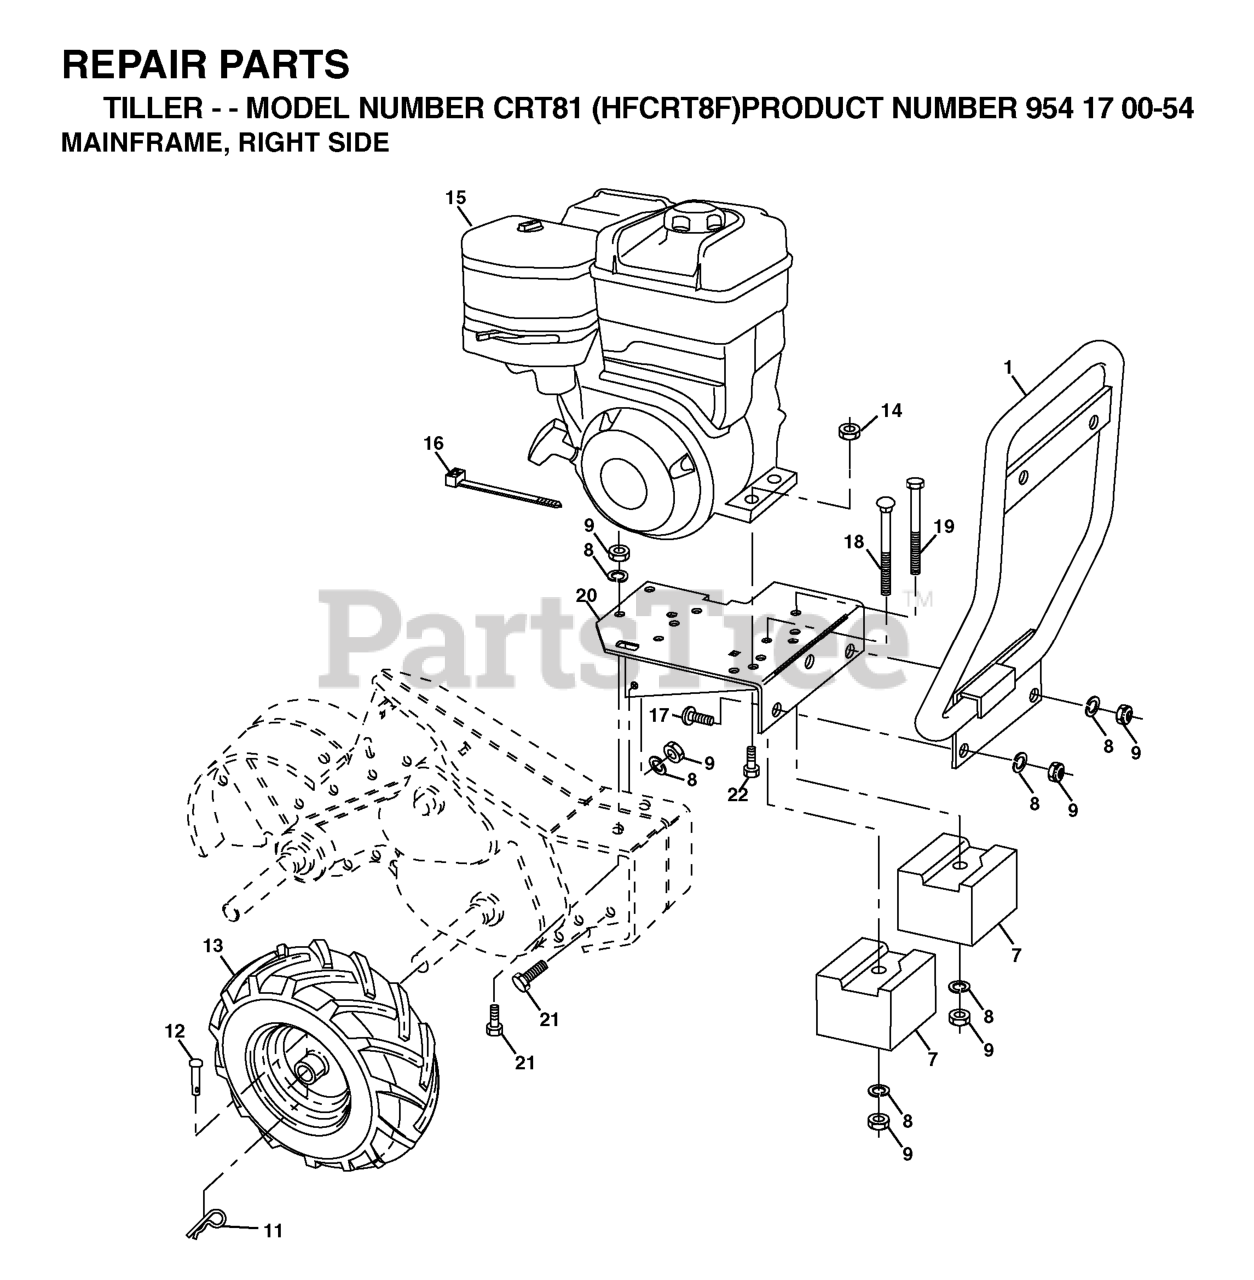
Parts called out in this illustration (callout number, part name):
1	BUMPER.ASM.9HP.TILLER
7	COUNTERWEIGHT
8	WASHER, LOCK 3/8
9	NUT.HEX.3/8-16UNC
11	SPRING TI
13	VALVE STEM LT
13	RIM
13	TIRE.16X4-8.CHEVRON.TILLER
14	LOCKNUT-FLANGE 5/16-18
16	TIE CABLE CRT
17	BOLT D
18	Bolt, Carriage 3/8-16 x 4-1/2
19	BOLT, HEX 3/8-16X4-1/2
21	BOLT
22	BOLT, HEX 5/16-18X1-3/4
